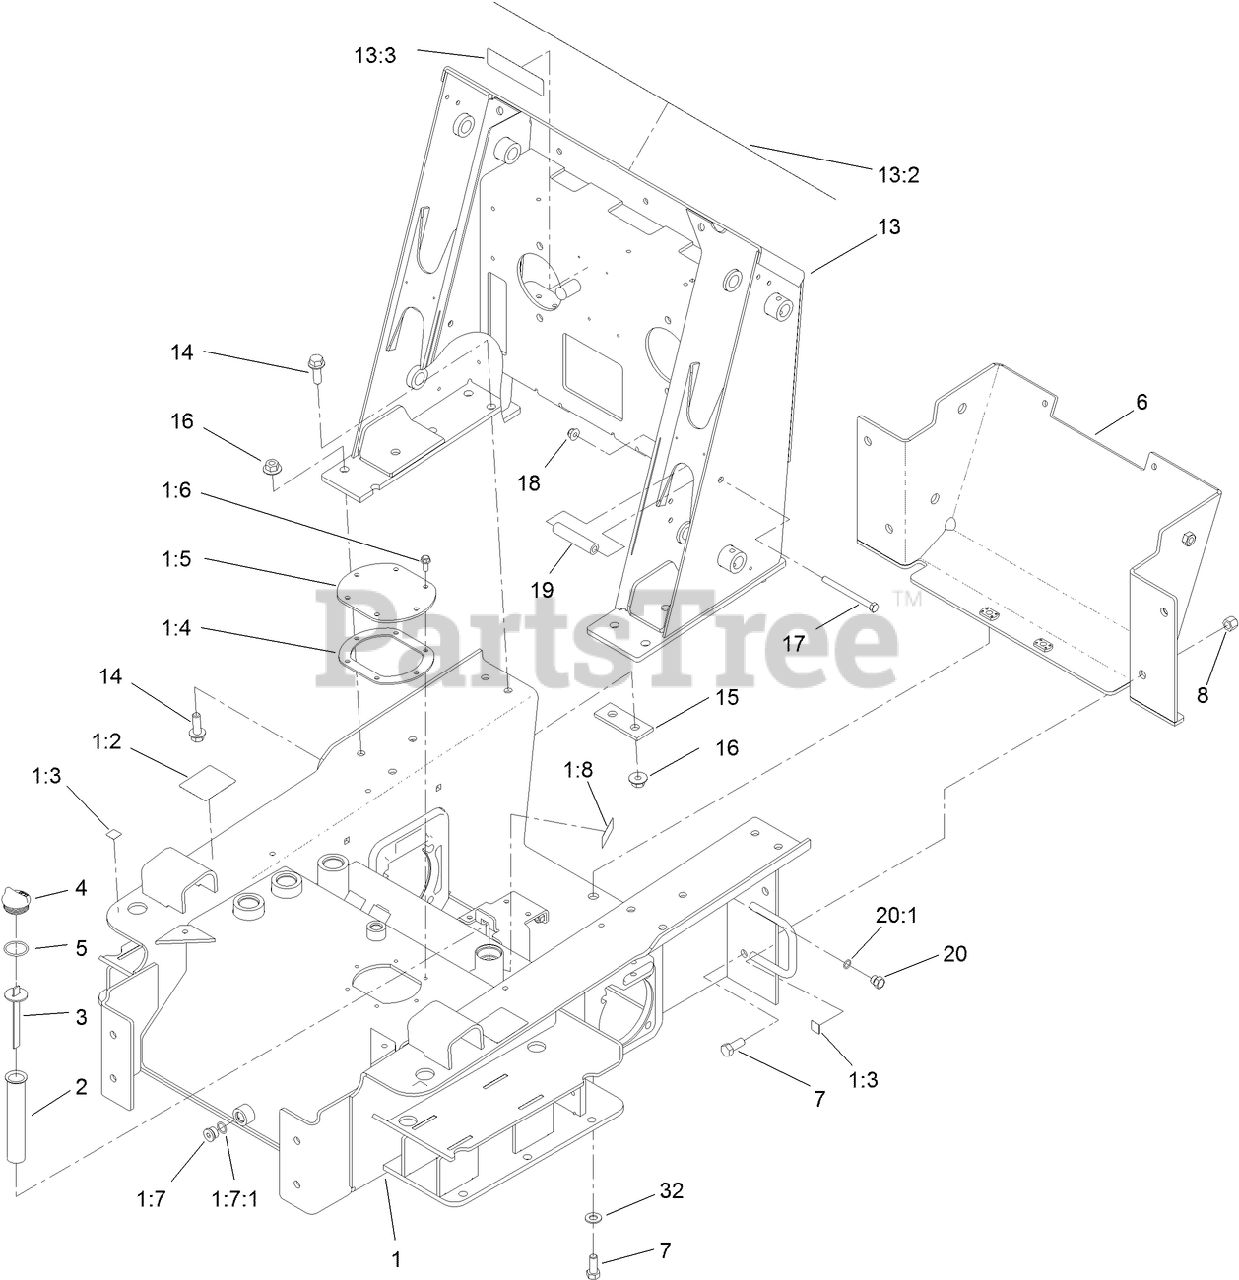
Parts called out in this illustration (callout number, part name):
1	CHASSIS ASM
1:2	DECAL-WARNING
1:3	DECAL-POINT, LIFT
1:4	GASKET-COVER, ACCESS
1:5	COVER-TANK
1:6	SCREW
1:7	PLUG-HEX
1:7:1	O-RING
1:8	DECAL-OIL, HYD
2	FILTER-SCREEN
3	DIPSTICK-OIL
4	PLUG-PLASTIC
5	O-RING
6	COVER-REAR
7	SCREW-HH
8	NUT-LOCK, NI
13	LOADER TOWER ASM
13:2	DECAL-PANEL, CONTROL
13:3	DECAL-DANGER
14	SCREW-HHF
15	PLATE-STIFFENER
16	NUT-LOCK, FLANGE
17	SCREW-HH
18	NUT-HF, NI
19	TUBE-SPACER
20	PLUG-HH
20:1	O-RING
32	WASHER-FLAT
